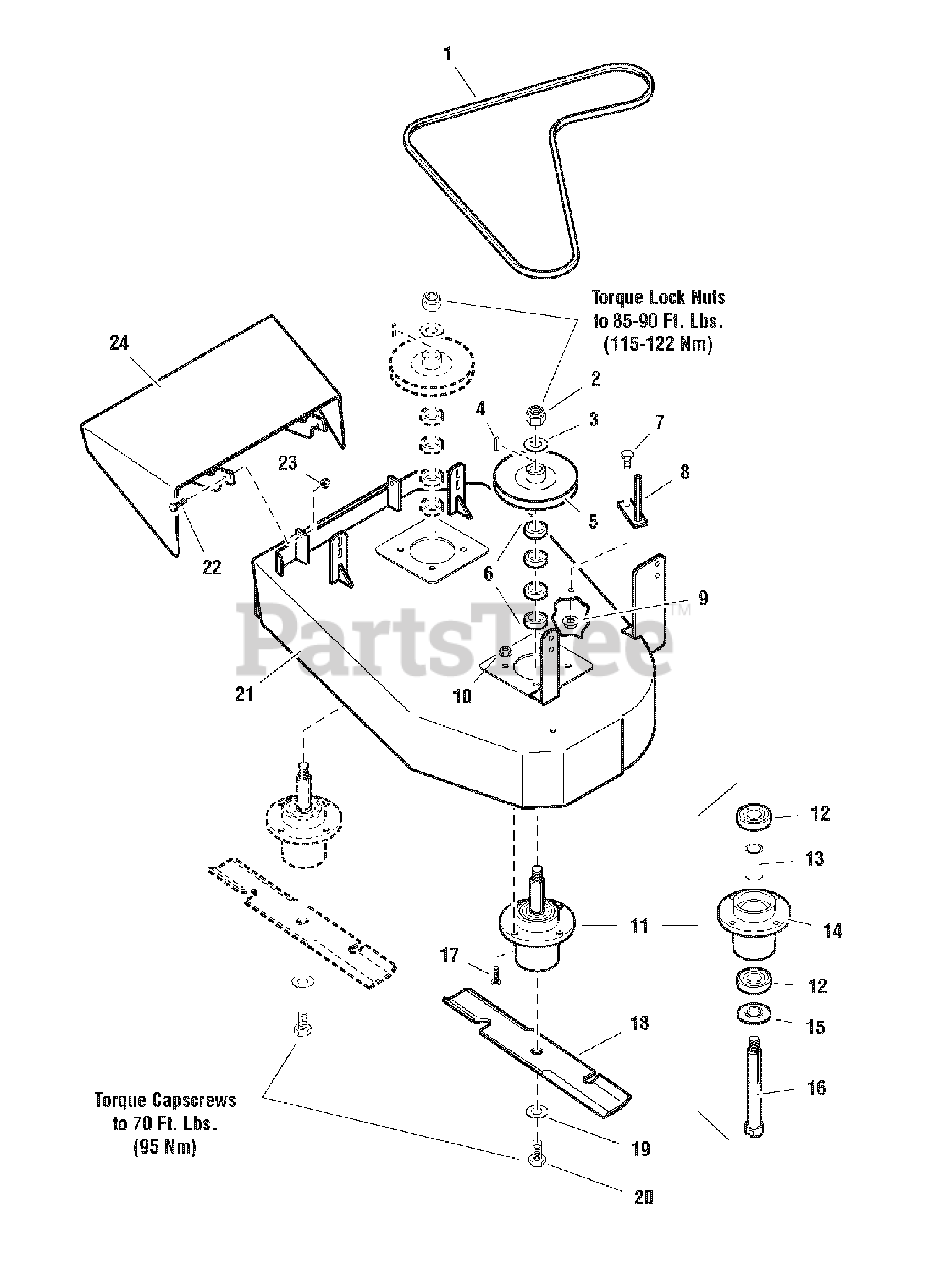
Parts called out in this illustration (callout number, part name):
1	BELT
2	NUT, Hex Nylon Lock, 5/8-18
3	WASHER, Spring, 5/8
4	KEY, 1/4 Sq. x 1
5	SPINDLE PULLEY
6	SPACER
7	BOLT, 3/8-16 X 1" GD5 CZ
8	BELT GUIDE
9	NUT, Hex Serrated Flange, 3/8-16
10	NUT, Hex Nylon Lock, 5/16-18
11	SPINDLE ASSEMBLY, Complete (includes ref 12-16)
12	BEARING, Ball
13	SPACER, Bearing
14	SPINDLE HOUSING
15	TRASH SHIELD
16	SPINDLE SHAFT
17	CAPSCREW, Hex Flange Head, 5/16-18 x 1-1/4
18	MOWER BLADE
19	WASHER, USS, 5/8
20	CAPSCREW, Hex Head, 5/8-11 x 1-3/4
21	MOWER DECK HOUSING, Complete (includes decals)
22	CAPSCREW, Hex Head, 5/16-18 x 1
23	NUT, HEX NYLON LOCK, 5/16-18
24	DISCHARGE CHUTE, Complete (includes decal)
